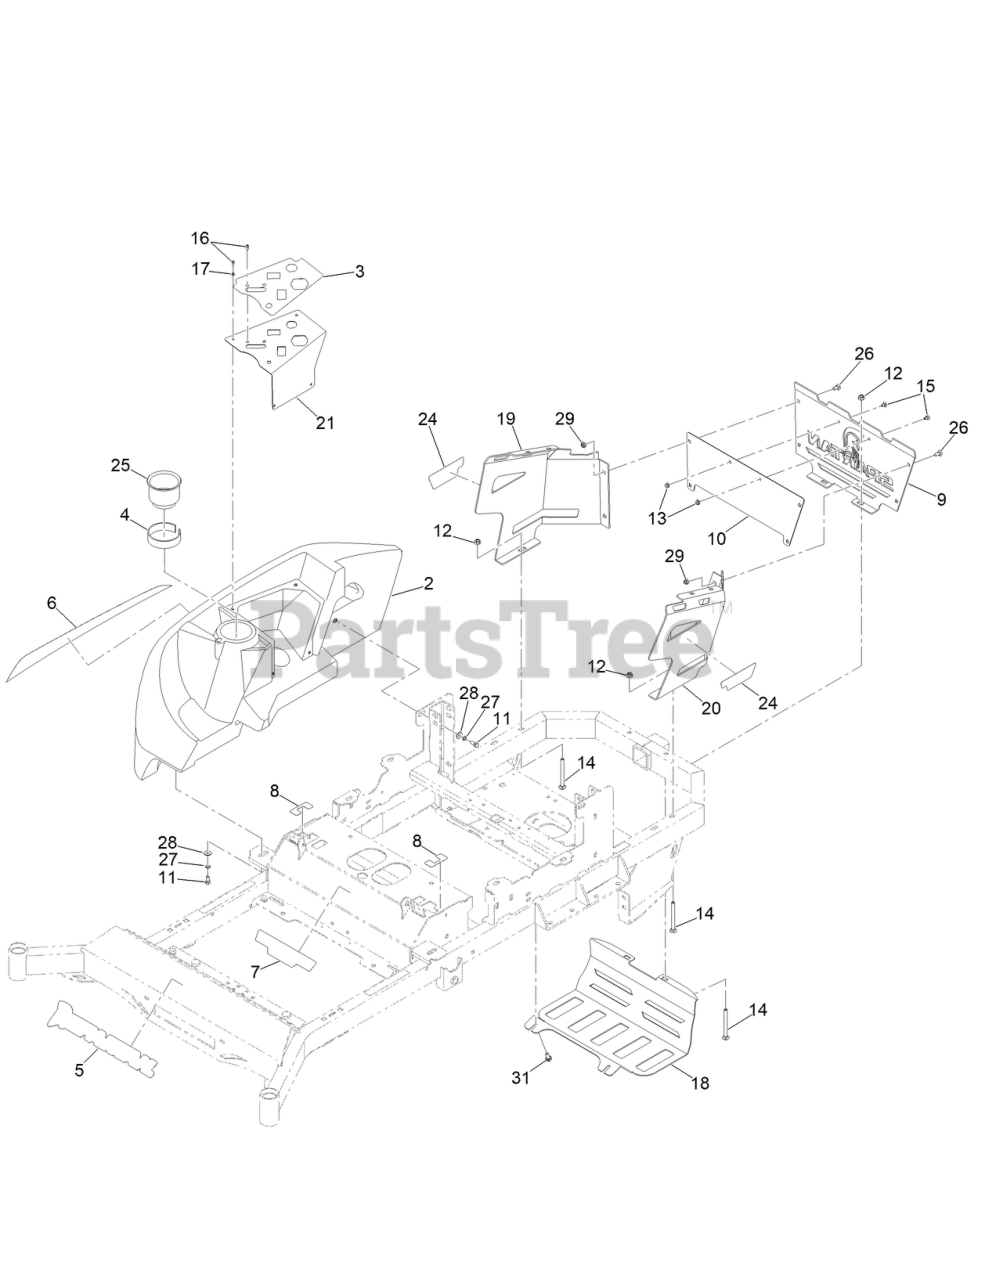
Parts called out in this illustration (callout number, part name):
2	CONSOLE W/ CUPHOLDER
3	DECAL-CONTROL PANEL
4	TAPE-FOAM
5	DECAL-SPARTAN, FRONT
6	DECAL-TANK
7	DECAL-RZ-HD GT TRAC MODEL
8	DECAL-MOTION CONTROL
9	PLATE - ENGINE COWLING
10	PLATE -BACKER PLATE
11	SCREW-HH
12	3/8-16 NYLON INSERT FLANGE L/NUT YZ
13	1/4-20 HEX FLANGE NUT W/SERR ZINC
14	3/8-16 X 4 CARRIAGE BOLT ZINC
15	1/4-20 X 1/2 CARRIAGE BOLT,YZ
16	10-24 X 1/2 SOCKET C/S 18-8 SS
17	#10 SPLIT LOCKWASHER 18-8 SS
18	MUFFLER GUARD [GRAY]
19	2021 RT/SRT ENGN COWLING RTPAINTED
20	2021 RT/SRT ENGN COWLING LT PAINTED
21	RT 45 KEY MNT
24	DECAL-MODEL
25	CUP HOLDER
26	BOLT-CARR
27	WASHER-LOCK
28	WASHER-FLAT
31	BOLT-HWH
